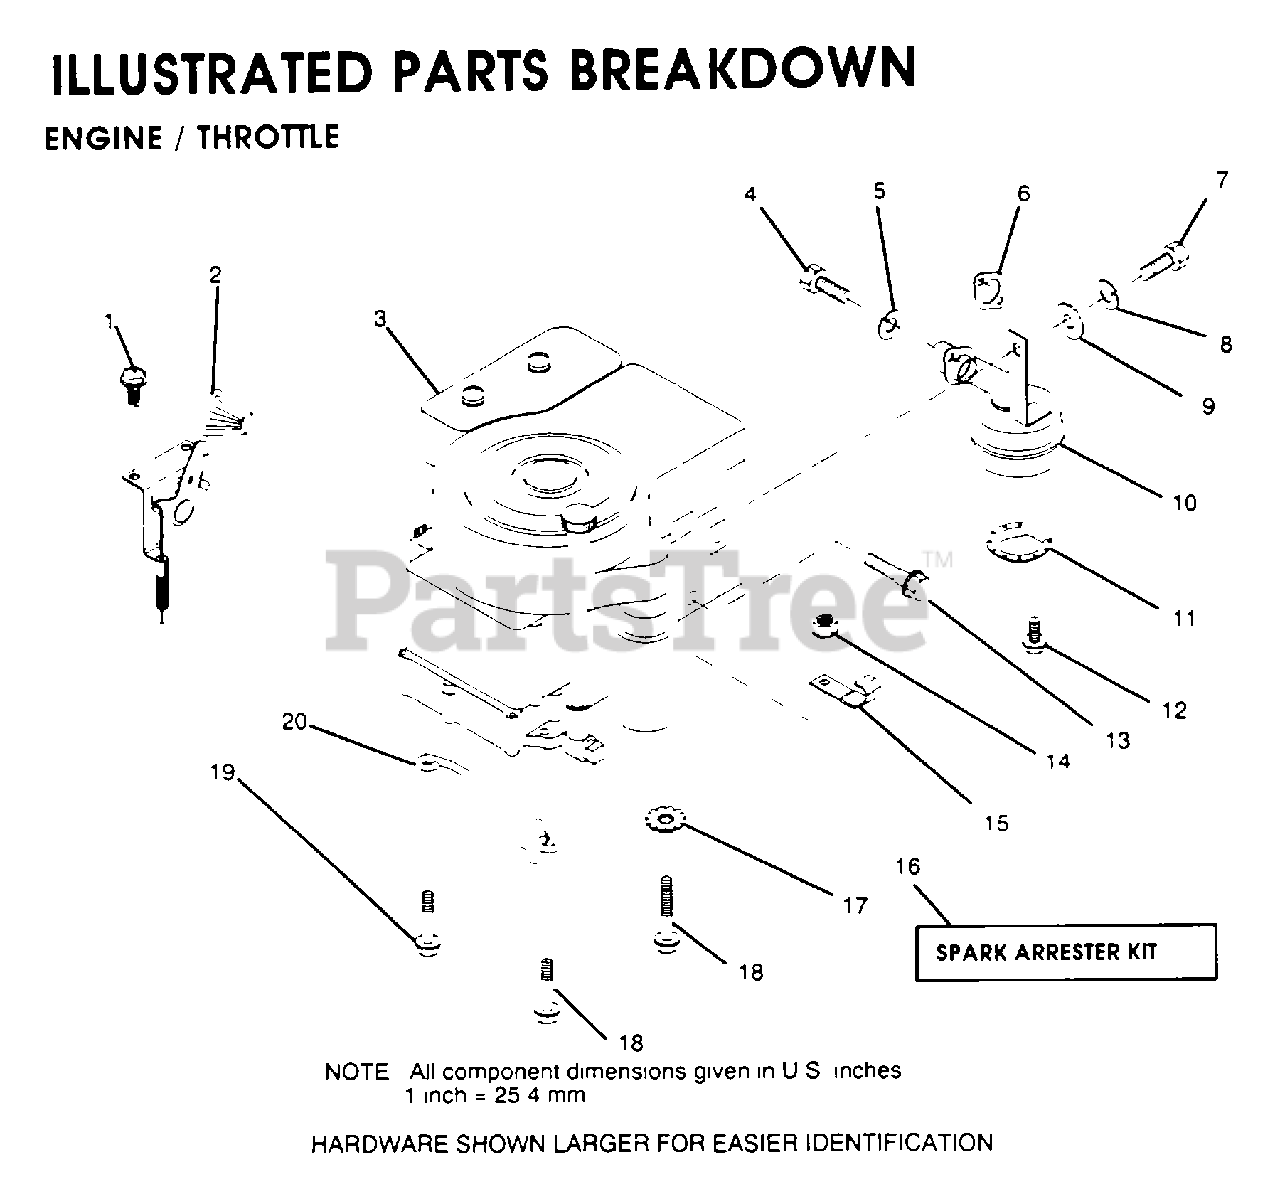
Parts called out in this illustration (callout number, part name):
1	SCREW
3	ENGINE BRIGGS AND STRATTON
4	SCREW
5	LOCKWASHER
8	LOCKWASHER
10	MUFFLER
11	DEFLECTOR.222573
13	BOLT T
14	NUT
15	CLIP T
17	LOCKWASHER
18	SCREW LT
19	SCREW LT
20	"KEEPER,DR BELT GR"
